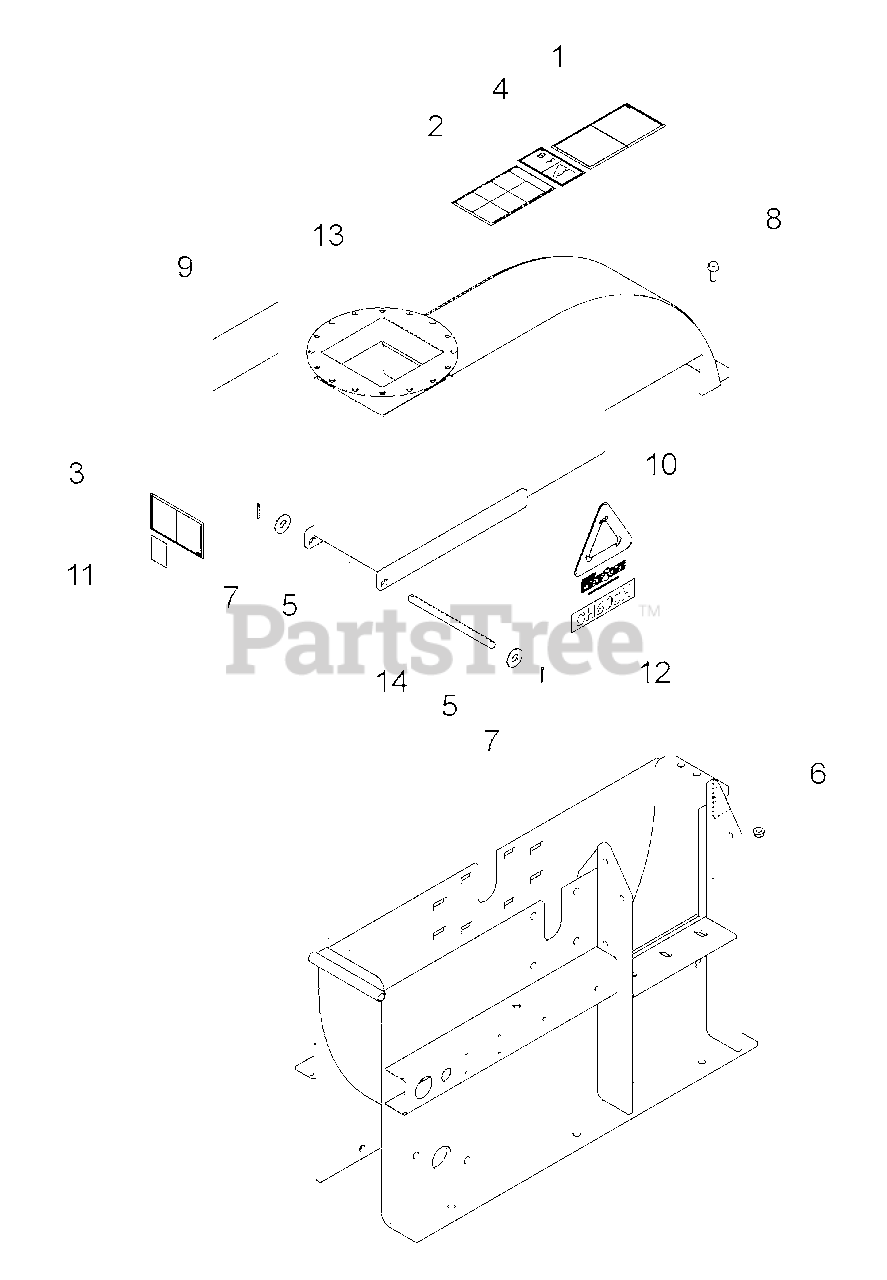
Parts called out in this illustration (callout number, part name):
1	DECAL, KNIFE ACCESS ISO
2	DECAL, OPERATING INSTRUCTIONS ISO
3	DECAL, DISCHARGE ISO
4	DECAL, MAINTENANCE ISO
5	WASHER, 1/2 FLAT
6	NUT, 3/8-16 SERRATED FLANGE
7	PIN, 1/8 X 1.00 ZP COTTER
8	BOLT, 3/8-16 X 1 SERRATED FLANGE GR5
9	DECAL, FLOW RATE HYDRAULIC
10	DECAL, CHIP IT
11	DECAL, ECHO BEARCAT QR CODE
12	DECAL, MODEL CH800H
13	WELDMENT, TOP CHIPPER HOUSING
14	SHAFT, CHIPPER TOP PIVOT
